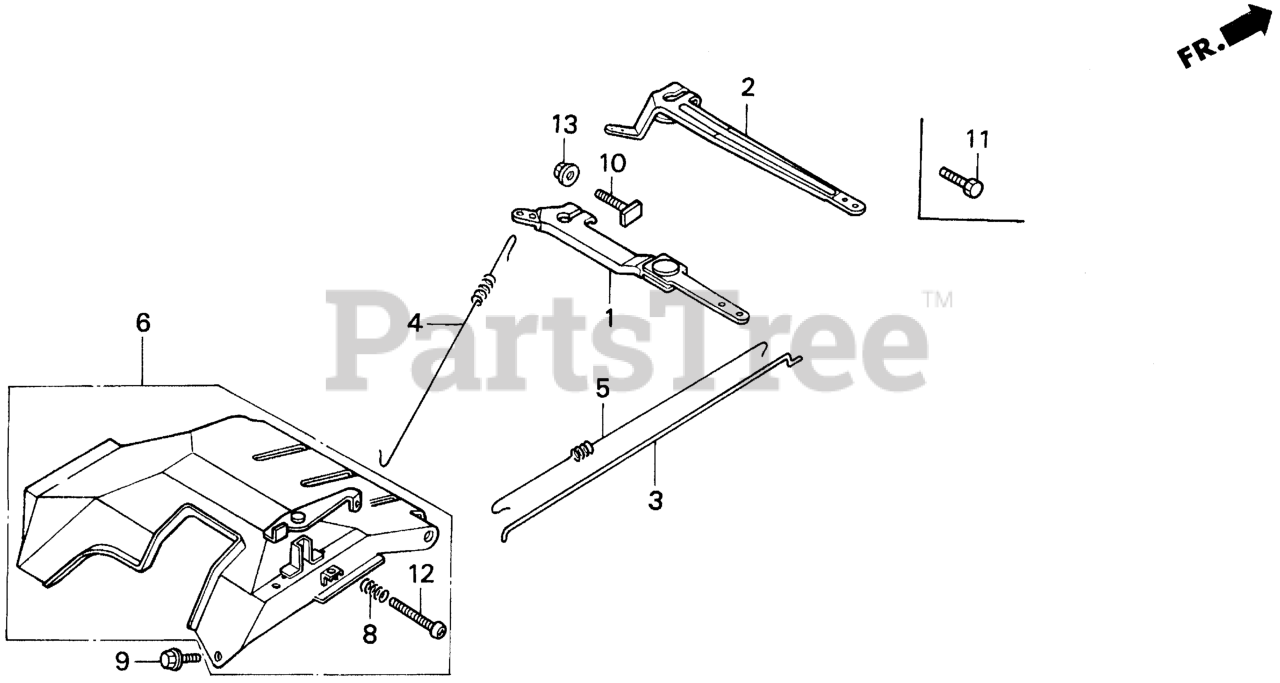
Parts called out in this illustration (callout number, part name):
2	ARM, GOVERNOR
3	ROD, GOVERNOR
4	SPRING, GOVERNOR (L=132.0MM)
5	SPRING, THROTTLE RETURN
6	CONTROL ASSY.
8	SPRING, CONTROL ADJUSTING Use from Engine SN 2327377.
9	BOLT, FLANGE (6X12) (CT200)
10	BOLT, GOVERNOR ARM
11	BOLT, HEX. (6X22)
12	SCREW, PAN (5X45)
13	NUT, FLANGE (6MM)
